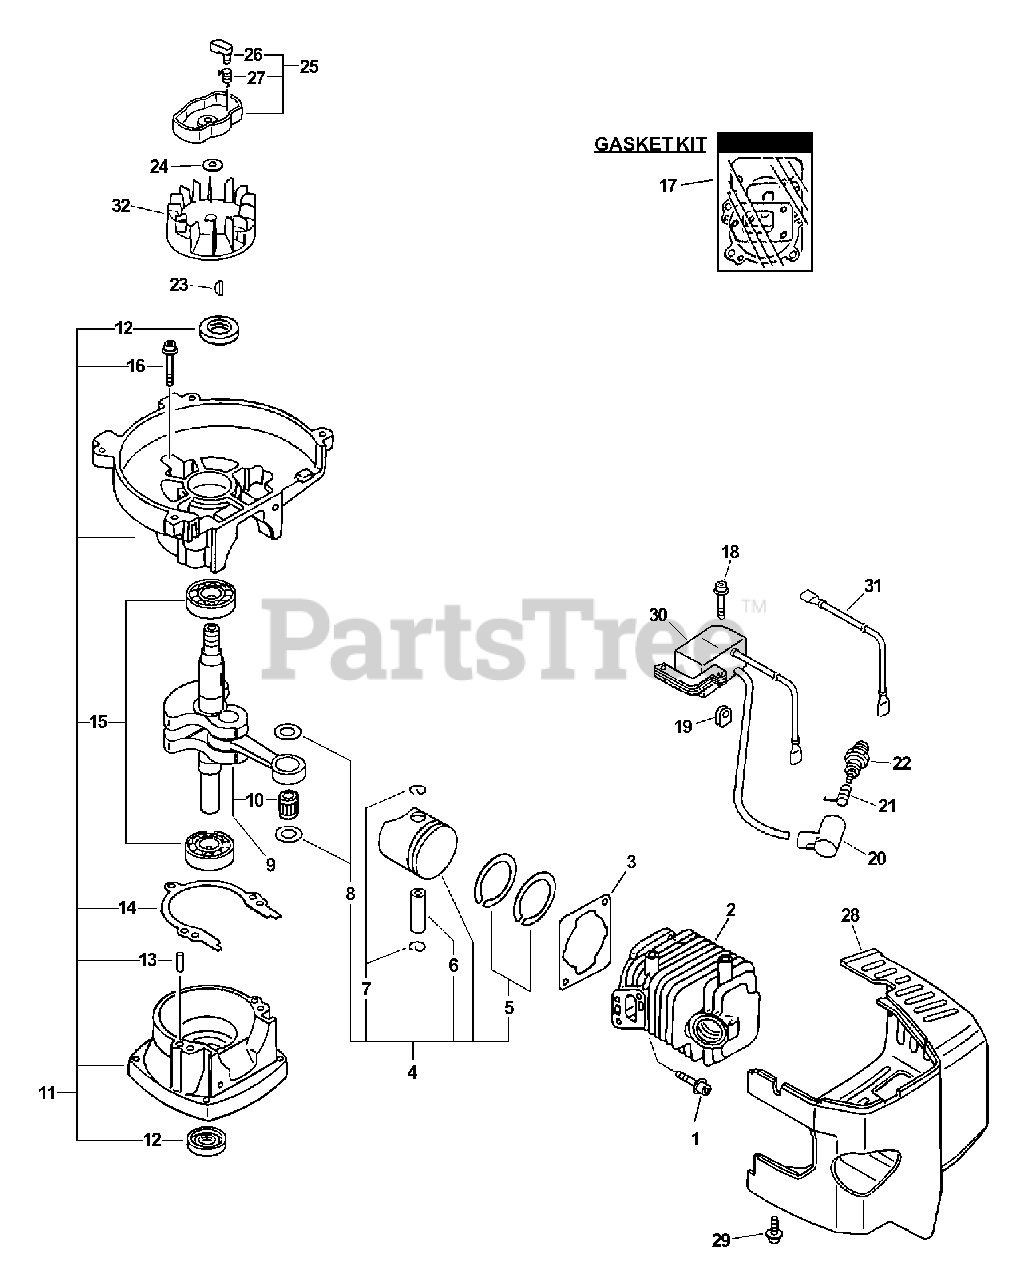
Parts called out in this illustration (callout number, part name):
1	SCREW - 5X22
2	CYLINDER
3	GASKET, CYLINDER
4	PISTON KIT
5	RING, PISTON
6	PIN, PISTON
7	RING, RETAINING
8	SPACER, PISTON
9	CRANKSHAFT ASSY
10	BEARING, NEEDLE - 8
11	CRANKCASE KIT
12	SEAL, OIL
13	PIN - LOCATING
14	GASKET, CRANKCASE
15	BEARING, BALL - 6201
16	SCREW - 5X28
17	GASKET KIT
18	SCREW - 4X22
20	CAP, SPARK PLUG
21	TERMINAL, SPARK PLUG CAP
22	SPARK PLUG -- BPM-7Y
24	LOCKWASHER - 8
25	STARTER PAWL ASSY
26	PAWL, STARTER - BLACK
27	SPRING, RETURN
28	COVER, ENGINE
29	SCREW - 4X18
30	COIL, IGNITION
31	LEAD - IGNITION
32	FLYWHEEL
